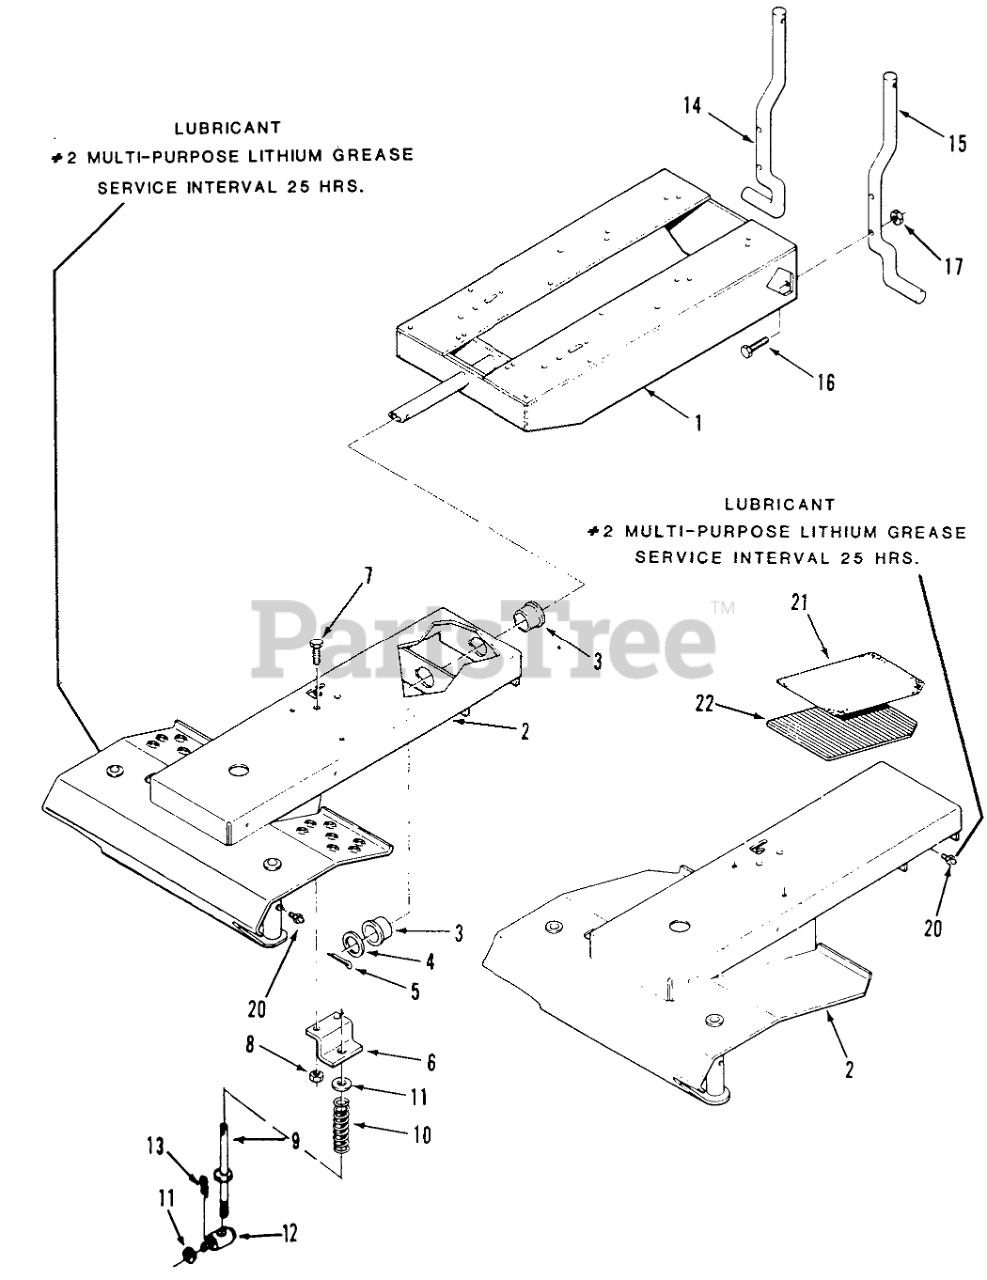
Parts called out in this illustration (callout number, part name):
1	ASS'Y-FRAME REAR R
2	ASSY FRONT FRAME R
3	BEARING FLANGE
4	WASHER
5	Pin-Cotter
6	BRACKET R
7	Bolt
8	NUT
9	ASSY ROD
10	SPRING-COMPRESSION
11	Washer
12	TRUNNION
13	Cotter Pin
14	REAR ROD RH B
15	REAR ROD LH B
16	Bolt
17	LOCKNUT 5/16-18GR.B
20	Grease Zerk
21	PAD FOOTREST RH
22	PAD FOOTREST RH
